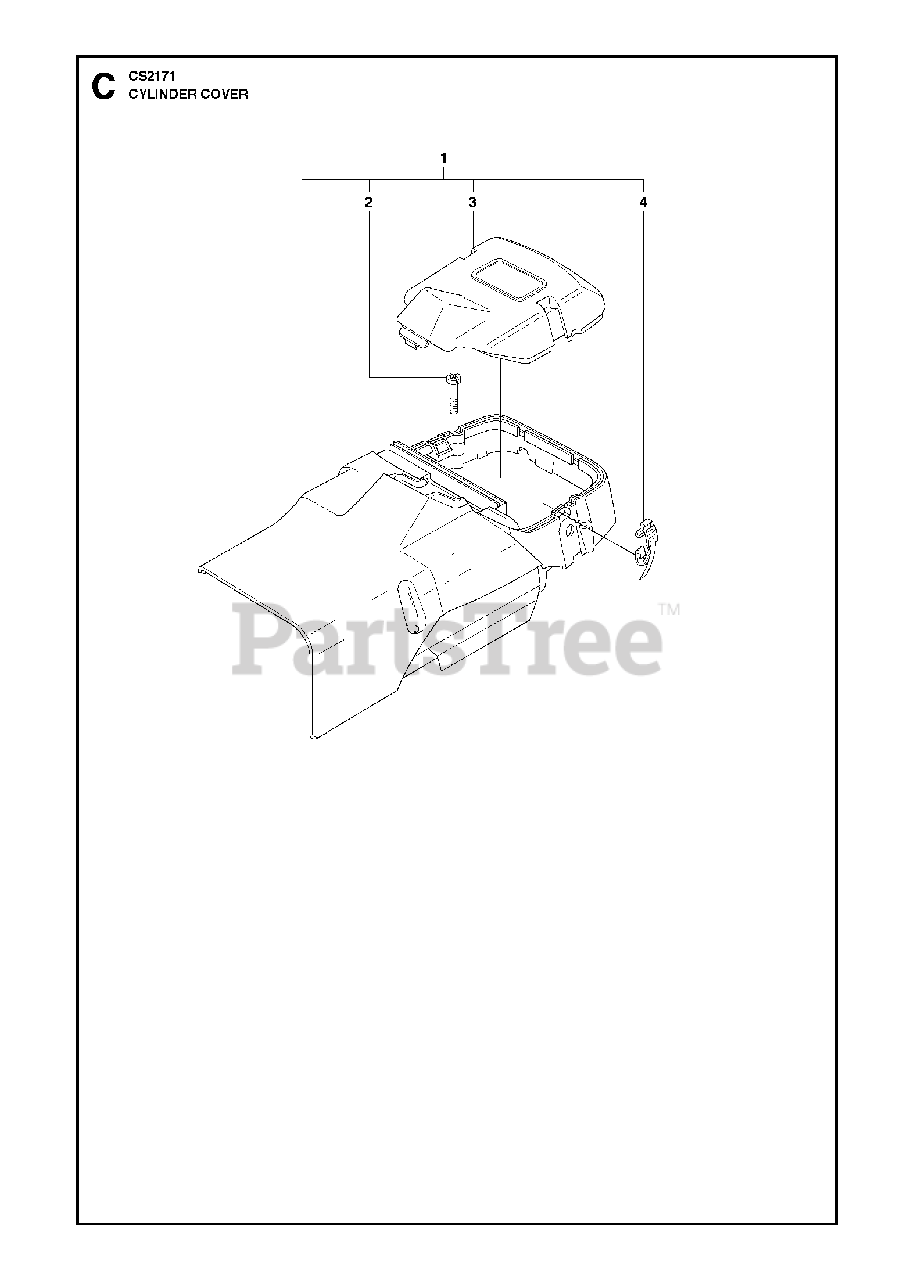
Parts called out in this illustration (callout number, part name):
1	CYLINDER COVER
2	SCREW
3	FILTERCOVER
4	CLIP
